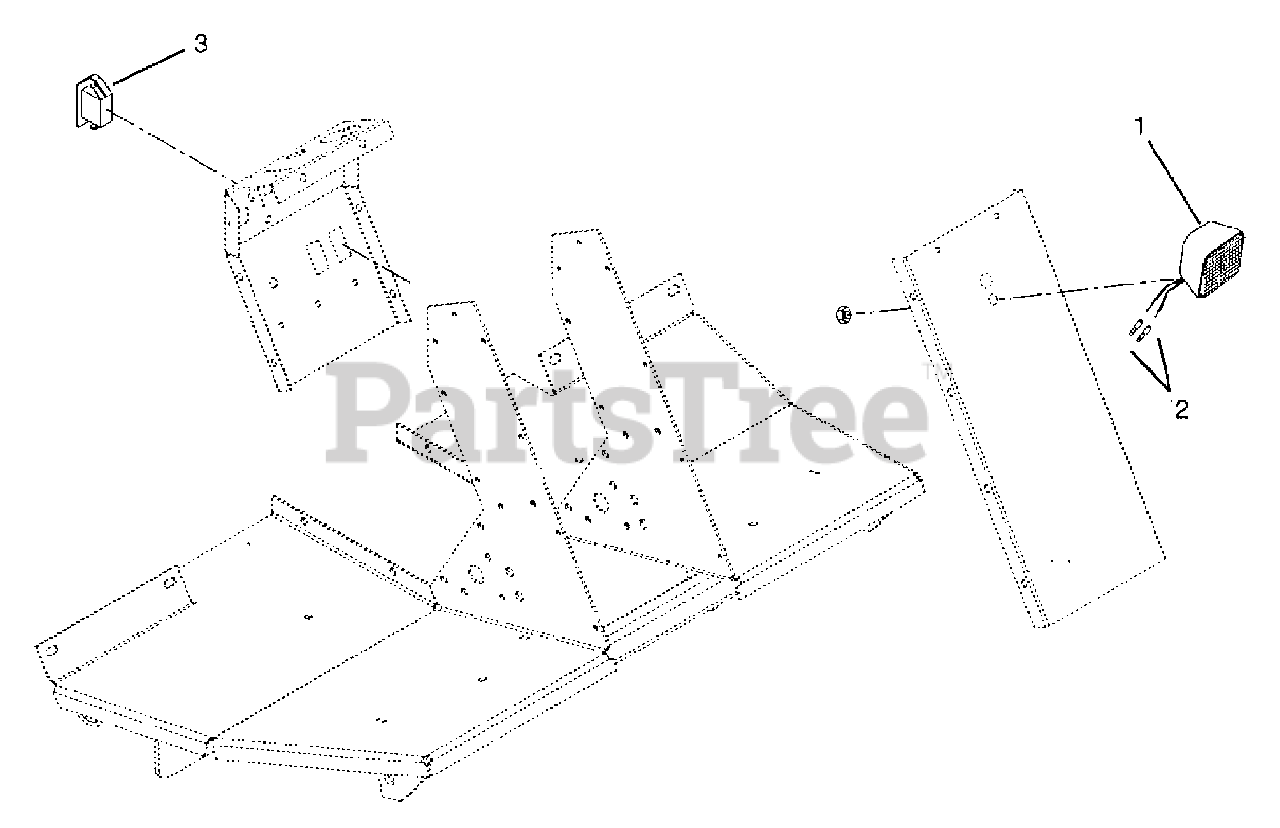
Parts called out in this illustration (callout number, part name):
1	Headlamp, 3 x 5 Halogen
2	Terminal, Male
3	Switch-Light
